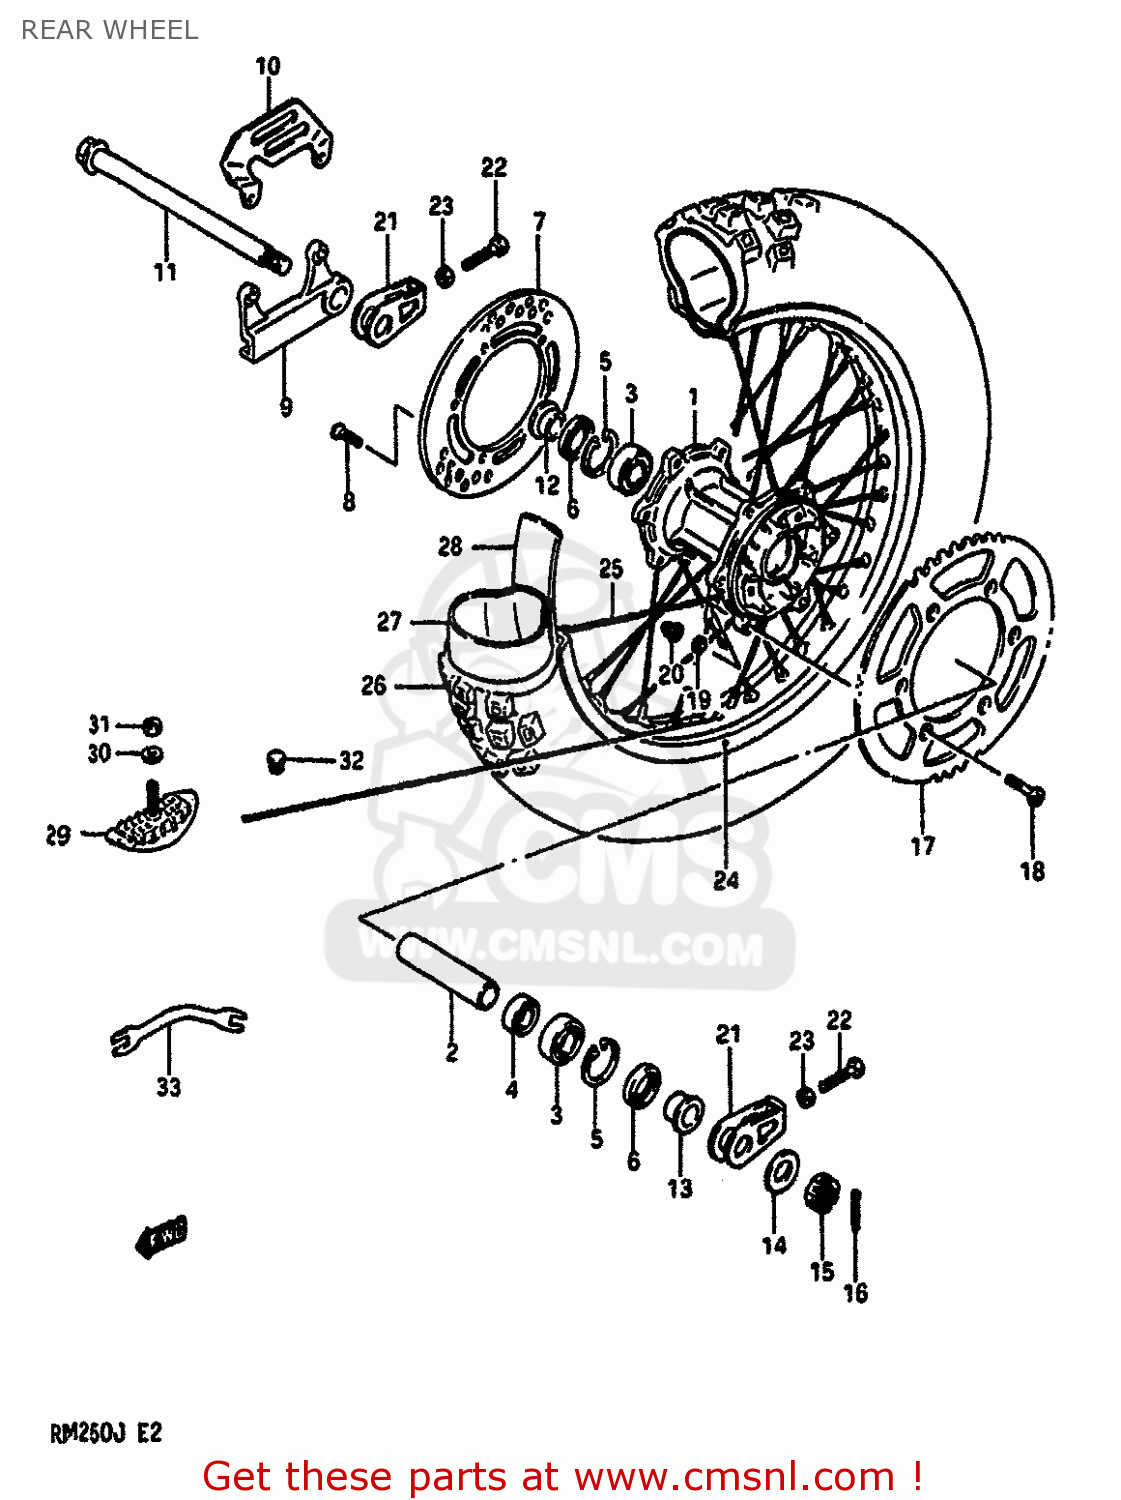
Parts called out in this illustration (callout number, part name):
1	HUB,REAR WHEEL
2	SPACER,RR HUB BEARING
3	BEARING
4	BALL BEARING
5	CIRCLIP,14MM
6	OIL SEAL
7	DISC,REAR BRAKE
8	SCREW
9	BRACKET,REAR CALIPER
10	GUARD,REAR CALIPER
11	AXLE,RR
12	SPACER,RR AXLE,R
13	SPACER,REAR AXLE,LEFT
14	WASHER (19X32X3.2)
15	NUT 18MM
16	PIN,COTTER
17	SPROCKET,REAR
18	SCREW(8X33.5)
19	WASHER
20	NUT
21	ADJUSTER COMP,CHAIN
22	BOLT L:50
23	NUT
24	RIM,REAR WHEEL
25	SPOKE ASSY,RR WHEEL
26	TIRE,REAR
27	TUBE,INNER
28	PROTECTOR
29	STOPPER,BEAD
30	WASHER
31	NUT 8MM
32	CAP(OD:12)
33	SPANNER,OPEN
